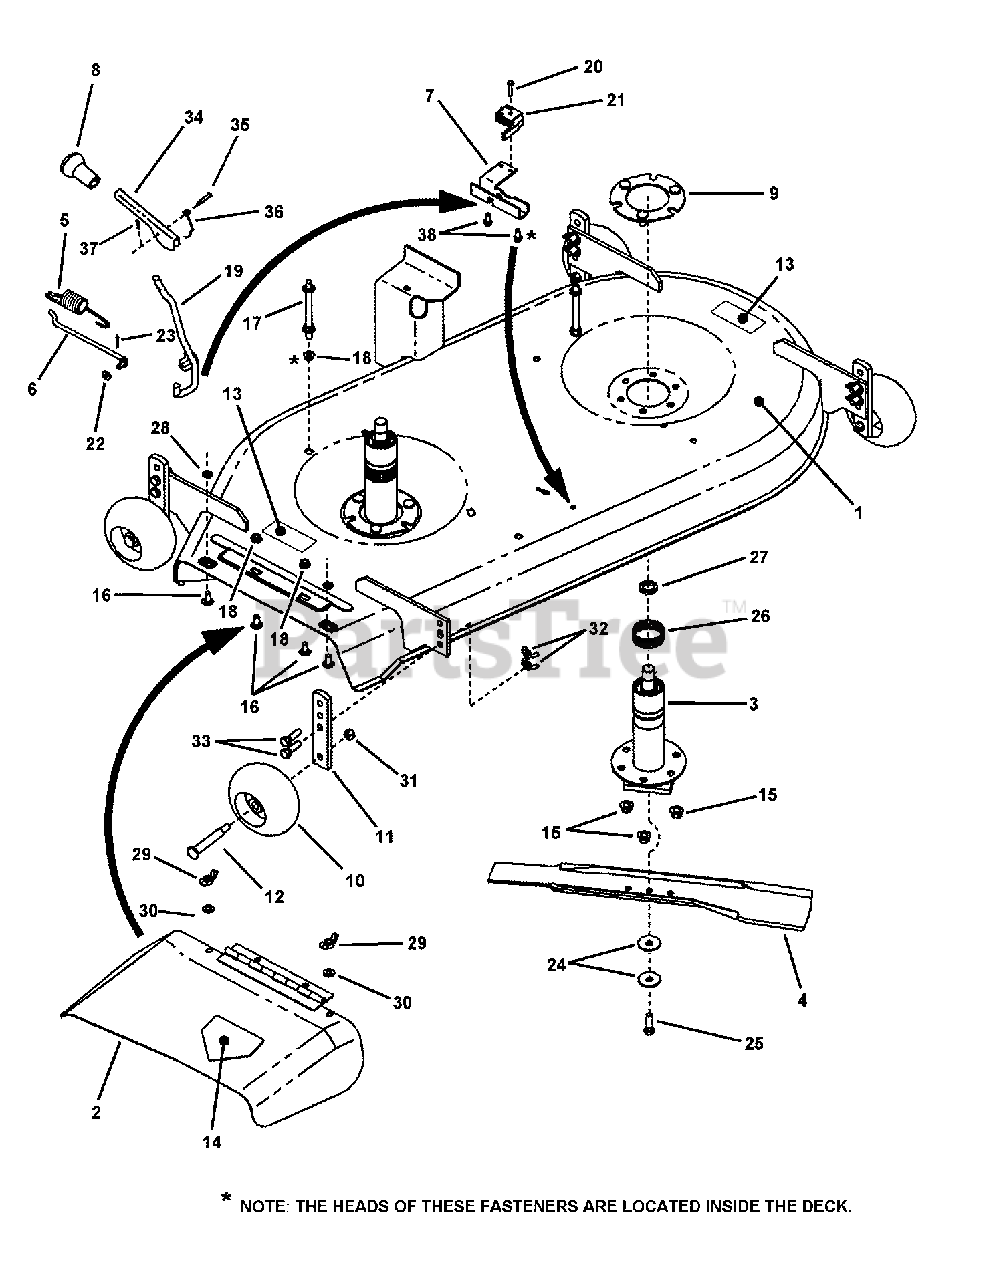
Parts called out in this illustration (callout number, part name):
1	WELDMENT, 42" Deck
2	ASSEMBLY, Side Chute (Includes decal 26831)
3	ASSEMBLY, Spindle
4	BLADE, 21" Standard Lift
5	SPRNG, Blade Handle
6	ROD, Idler Control
7	MOUNT, Handle/Switch
8	GRIP, Handle
9	ASSEMBLY, Spindle Ring
10	WHEEL, Gage
11	POST, Anti-Scalp
12	BOLT, Gage Wheel, 3/8-16 x 3-3/8" Hex Head Shoulder
13	DECAL, Caution
14	DECAL, Danger
15	NUT, 3/8-16 Hex Flange Lock
16	BOLT, 5/16-18 x 3/4" Short Neck Carriage, GR5
17	STAND-OFF, 3-1/2" long, 5/16-18 top, 3/8-16 bottom threads
18	NUT, 3/8-16 Hex Flange Lock
19	WELDMENT, Blade Engagement Handle
20	SCREW, #10-32 x 1" Hex Washer Head Self-Tap
21	SWITCH, Deck Interlock (NO)
22	WASHER, 1/4" Flat
23	PIN, 3/32 x 3/4" Cotter
24	WASHER, 13/32" I.D. Cone
25	SCREW, 3/8-24 x 1-1/4" Hex Head Cap, GR5
26	TOLERANCE RING, 2.0
28	RETAINER, 5/16" Bolt
29	WING-NUT, 5/16-18 Lock
30	WASHER, 5/16" Flat
31	NUT, 3/8-16 Hex Center Lock
32	WING-NUT, 3/8-16 Nyloc
33	SCREW, 3/8-16 x 1-1/4" Hex Head Cap, GR5
34	HANDLE, Blade Engagement
35	PIN, 3/16 x 1" Clevis
36	SPRING, Torsion
37	PIN, 3/32 x 1/2" Cotter
38	SCREW, 1/4-20 x 5/8" Hex Washer Head Self-Tap
